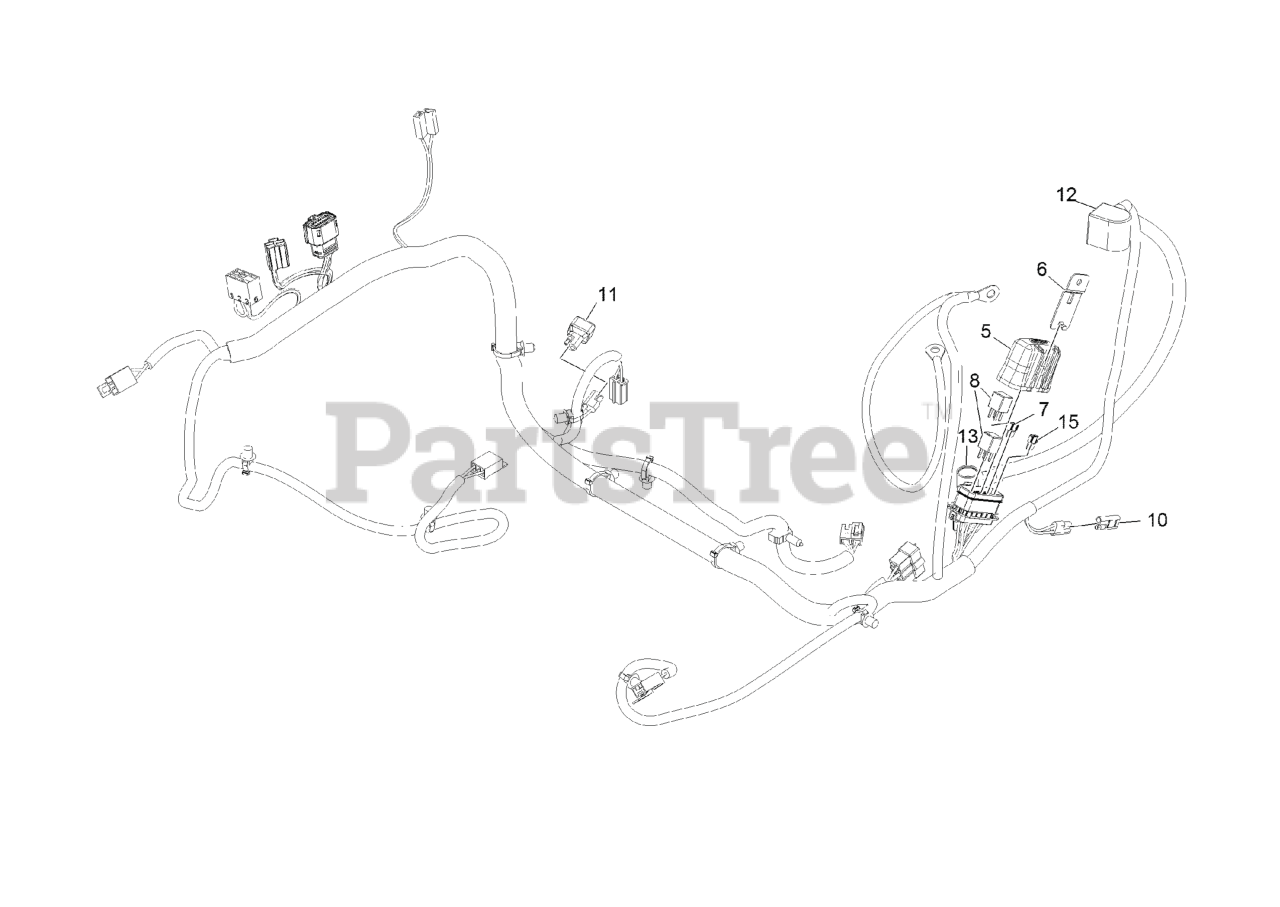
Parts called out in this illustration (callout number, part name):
5	COVER-BLOCK, FUSE
6	CLIP-MOUNTING
7	FUSE-MINI BLADE, 20 AMP
8	RELAY-MICRO
10	CAP-PLUG
12	INSULATOR-BATTERY
13	INSULATOR-SOLENOID
15	FUSE-MINI BLADE, 15 AMP
